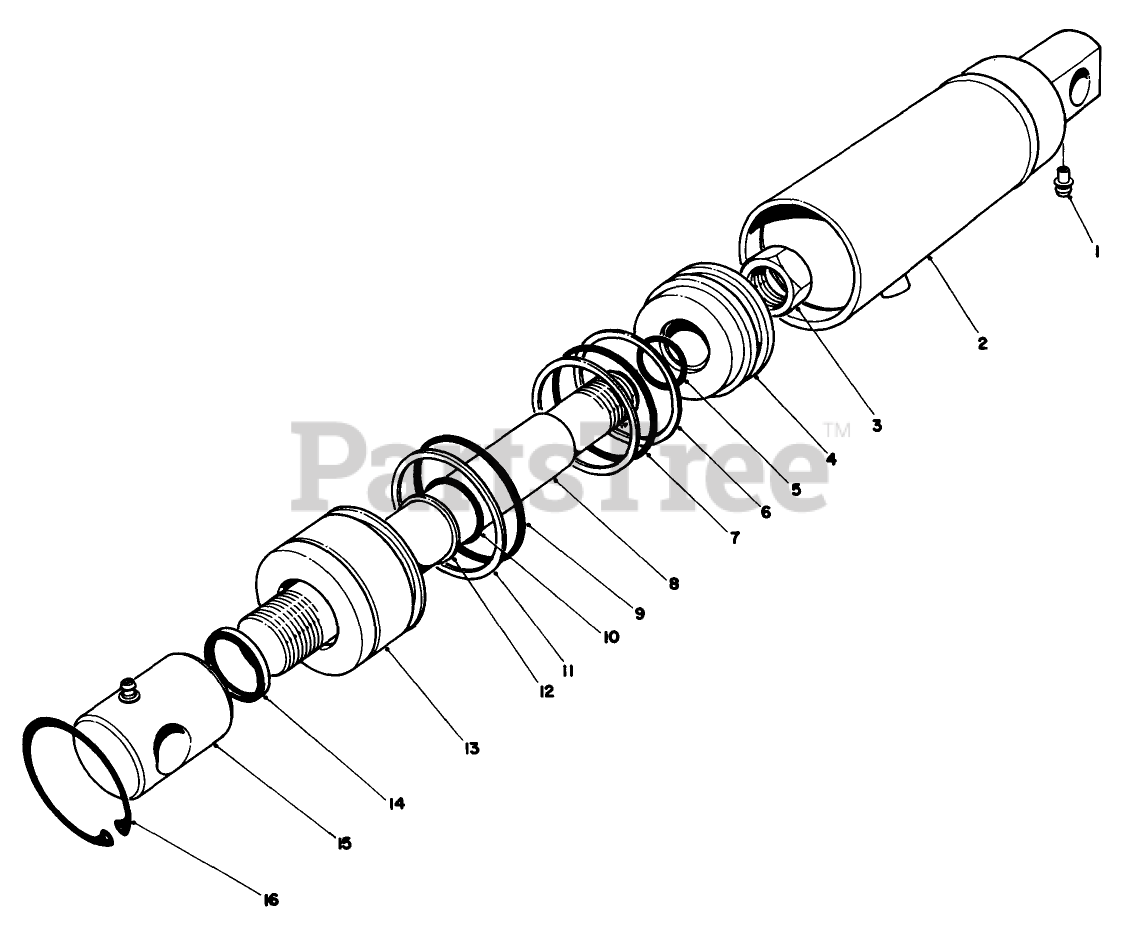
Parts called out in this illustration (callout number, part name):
1	FITTING-GREASE
2	Barrel Assembly
3	Nut-Lock
4	Piston Gland
5	O-Ring
6	Ring-Back-Up
7	O-Ring
9	O-Ring
10	O-Ring
11	Ring-Back-Up
12	Ring-Back-Up
13	HEAD GLAND
14	Wiper-Rod
15	ROD CLEVIS
16	Ring-Snap
